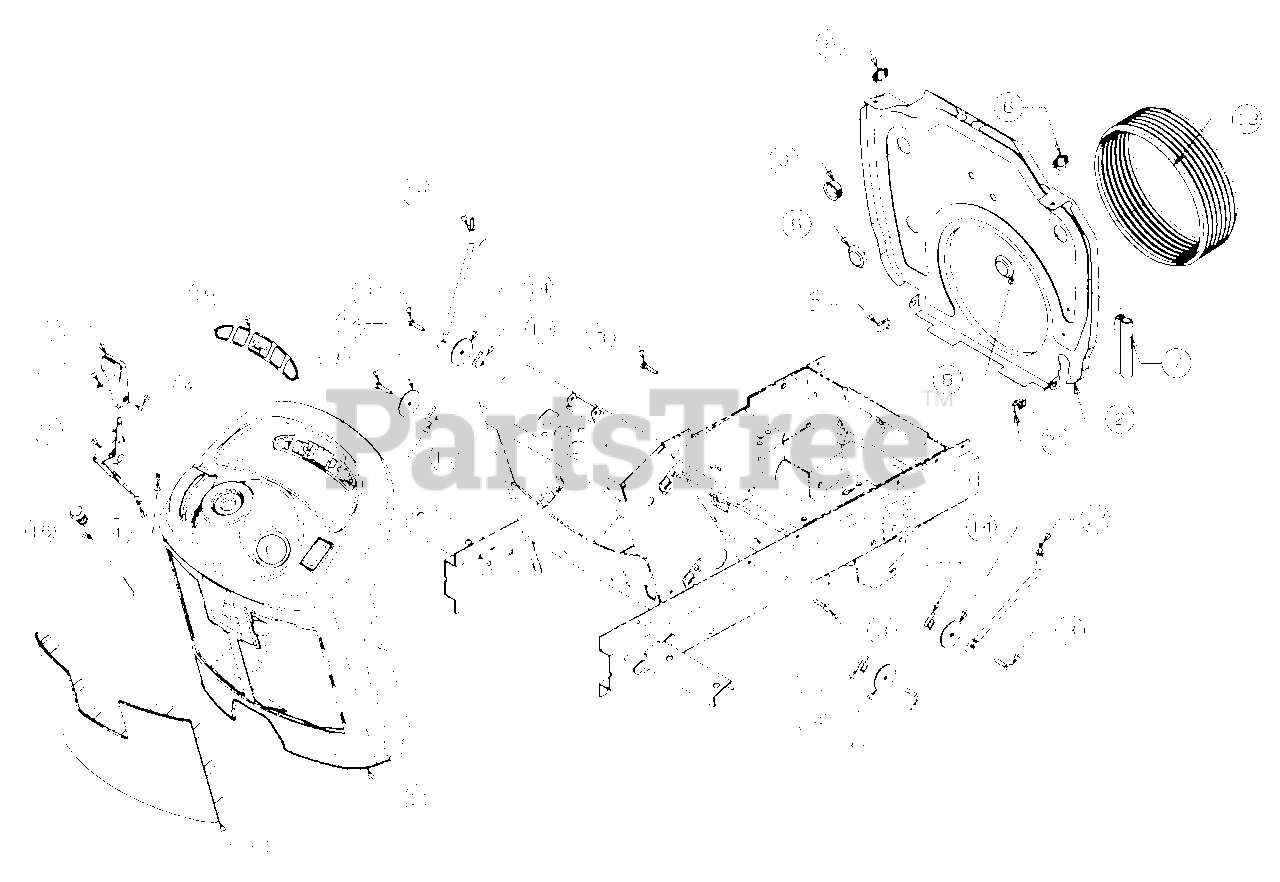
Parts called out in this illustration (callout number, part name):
2	Bulkhead, Lower
3	Screw, Hex Cap, 1/4-20 x 1.0 Lg GR2
4	Screw, Cross Rec Truss Hd #8-32 x .38 Lg
5	Nut, #8-32
6	Nut, Wing w/Bell Washer, 1/4-20
7	Seal, Push-on Trim, 14" Lg
8	Plug, Button, 1.12 Dia
9	Bushing, Snap, 7/8 ID
10	Nut, U-Clip, 1/4-20
11	Panel, Dash
12	Knob, Throttle
13	Boot, Intake
14	Washer, Flat, .285 x 1.75 x .10 Thk
15	Control, Throttle
16	Control, Choke
17	Rod, RH Mounting
18	Rod, LH Mounting
19	Label, Dash
20	Nut, U-Type Speed, 1/4-20
